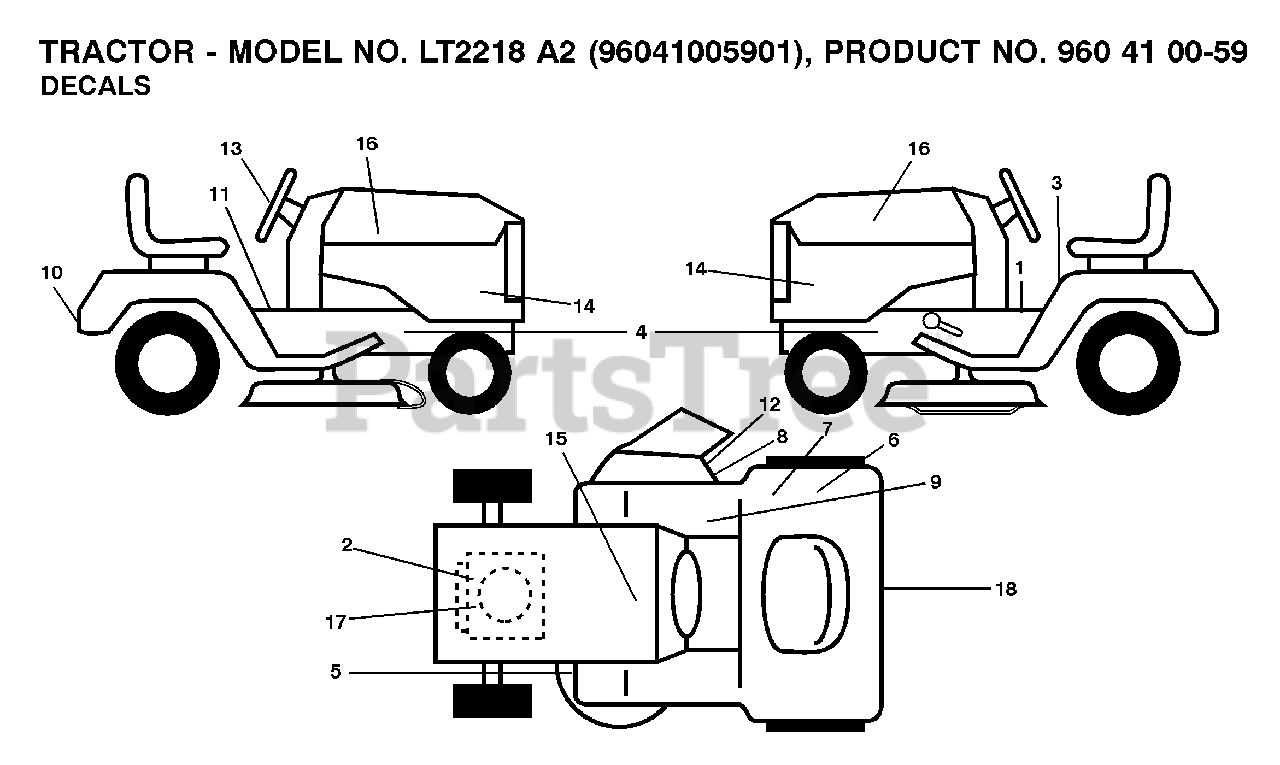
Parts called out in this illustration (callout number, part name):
1	DECAL PARK BRAKE
5	DECAL V BELT SCHEMATIC
7	DECAL.80 DBA.AUSTRALIA
8	DECAL, DEFLECT WARNING
12	DECAL.INTERNATIONL.CUTFINGER
15	DECAL BTRY SYMBOLS
